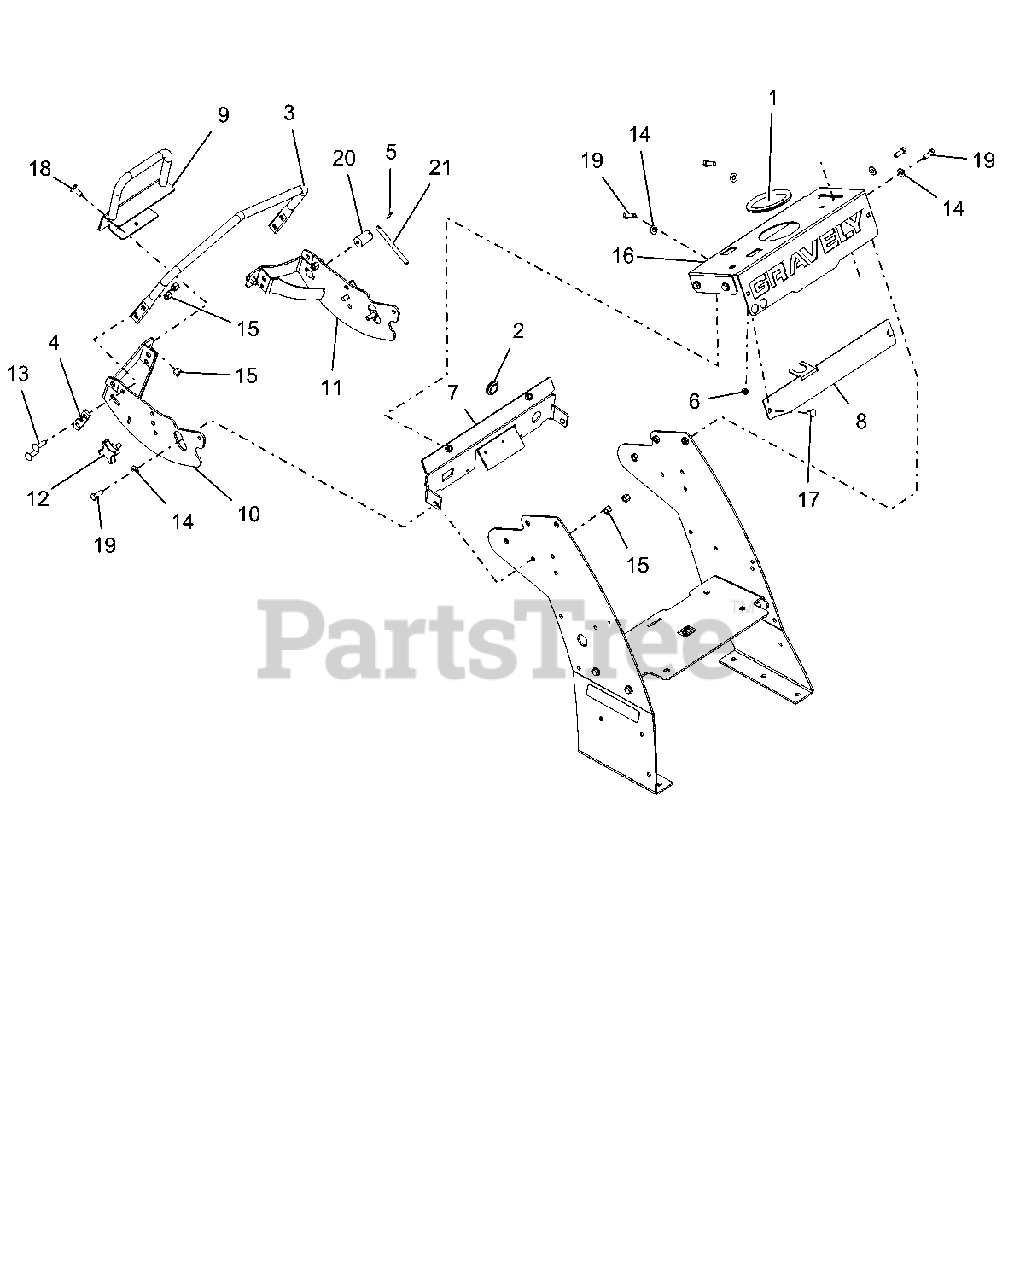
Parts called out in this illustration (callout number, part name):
1	TRIM, RUBBER DEGE 12"
2	GROMMET:RUB:.88IDx1.38ODX.14GR
3	SUPPORT, HANDLE-RED
4	SHIM, BAR 5 DEG SPEED-RED
5	PIN, SPRING
6	NUT-LK-NYL .312-18 YWZC
7	WLDMT, HANDLE BRACE-RED
8	BRACKET, REMOTE ROV HYDRO-BLACK
9	WLDMT, REVERSE BAR (RED)
10	WLDMT, RH CONTROL MOUNT-RED
11	WLDMT, LH CONTROL MOUNT-RED
12	KNOB, 3/8-16 x .75
13	BLT-RDHDSQNK .38-16X1.25 G5 YWZC
14	WSHR-FL-STL.406X.812X.065 YWZ
15	NUT-LK-NYL .38-16 YWZC
16	CONSOLE, W/ DECAL, GRV PS MY13
17	BLT-RDHDSQNK .31-18X.75 G5 YWZC
18	BLT-RDHDSHSQNK.38-16X1.0 G5YZ
19	BLT-HEX .38-16X1.00 GR5 YWZC
20	BASE, LOCK LEVER Y
21	LEVER, LOCK Y
